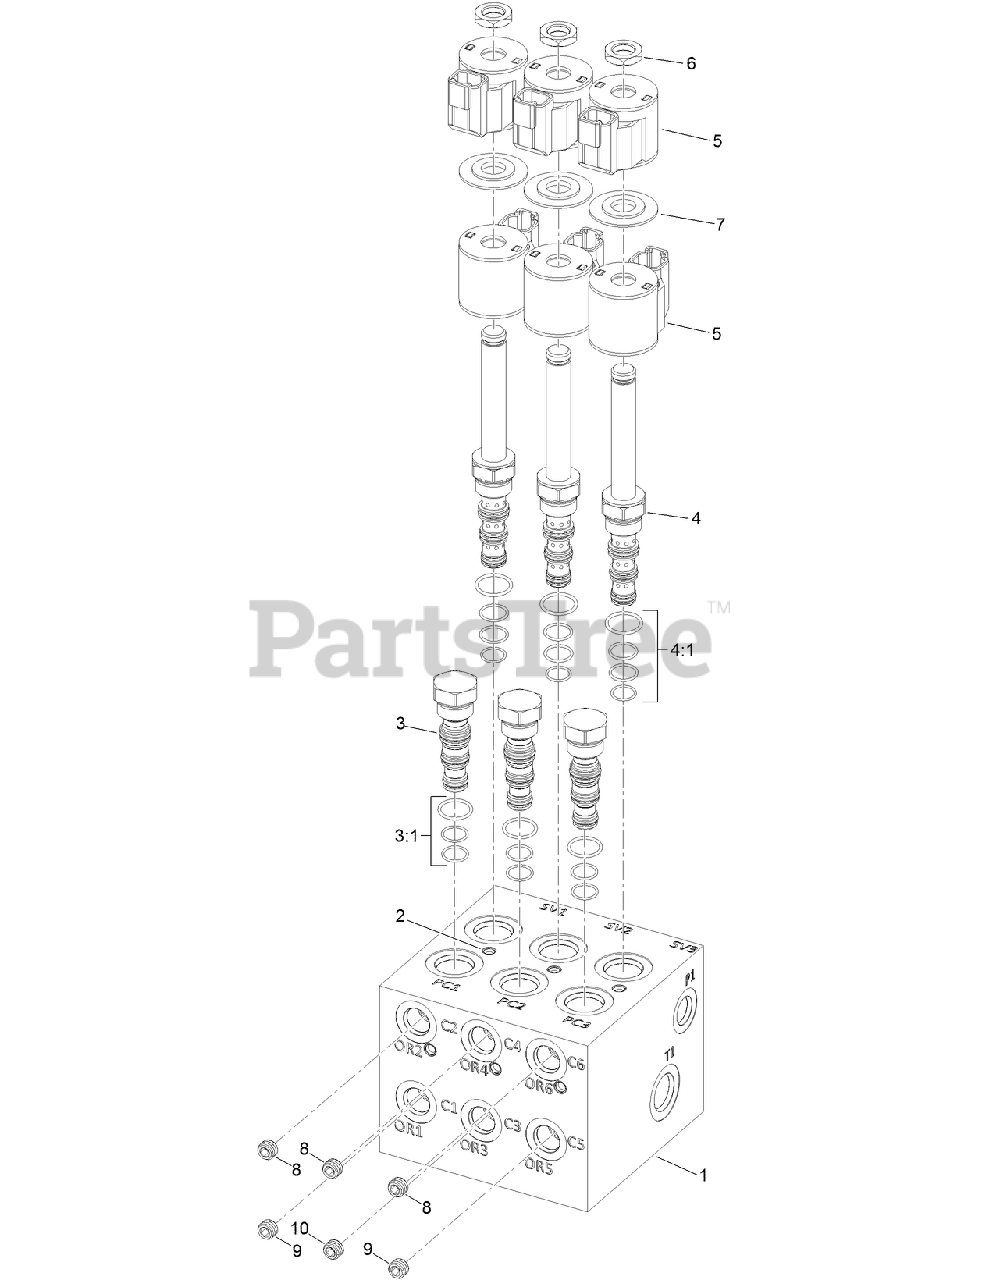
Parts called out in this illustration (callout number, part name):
1	BLOCK-MANIFOLD
2	Deck ASM
3	VALVE-CHECK
3:1	SEAL KIT
4	VALVE-SOLENOID
4:1	SEAL KIT
6	NUT-COIL
7	SPACER-COIL
8	ORIFICE-FLOW, CONTROL (.060)
9	ORIFICE (.063 INCH)
10	PLUG-ORIFICE (.067)
